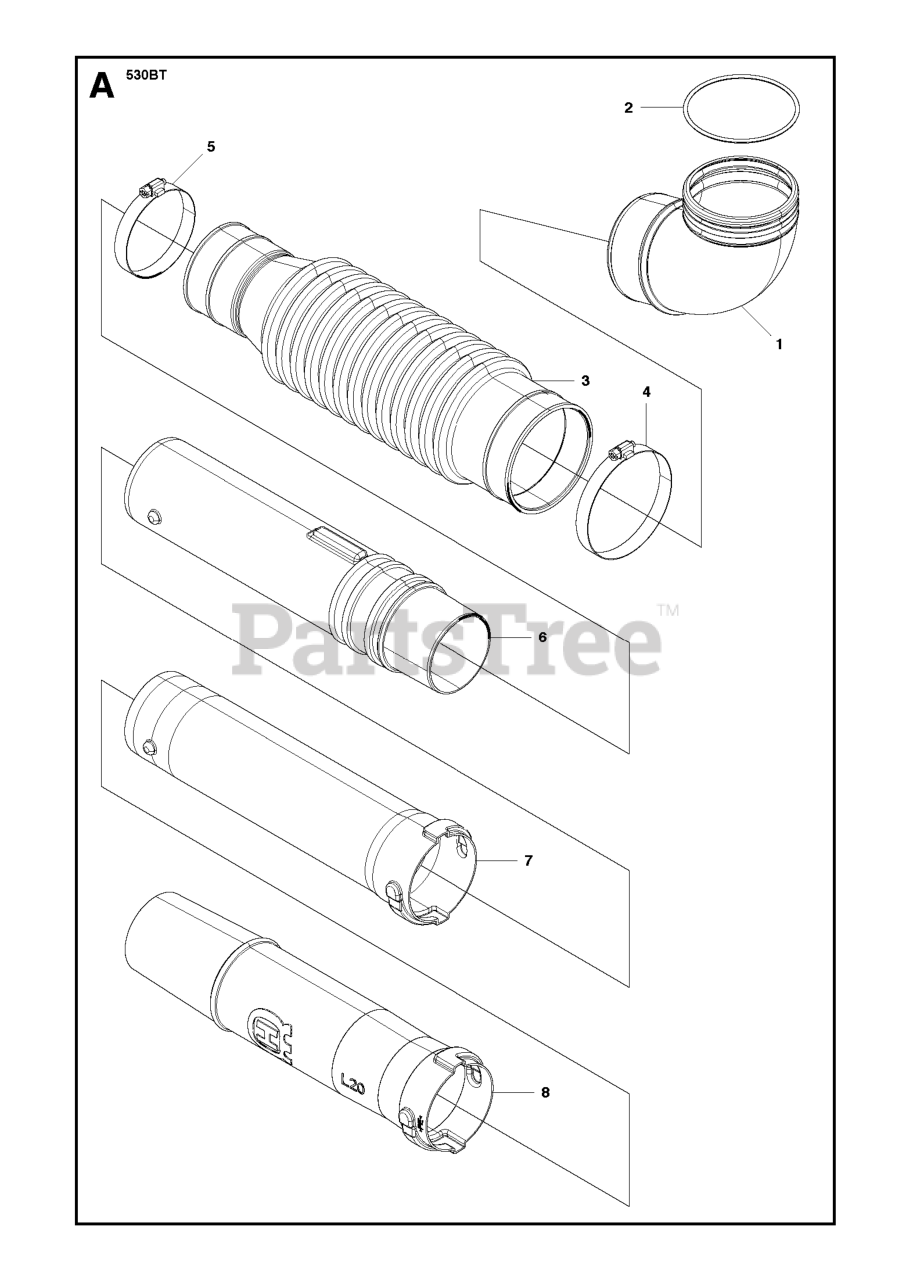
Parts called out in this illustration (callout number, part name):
5	CLAMP(F96)
6	SWIVEL JOINT
7	PIPE STRAIGHT
